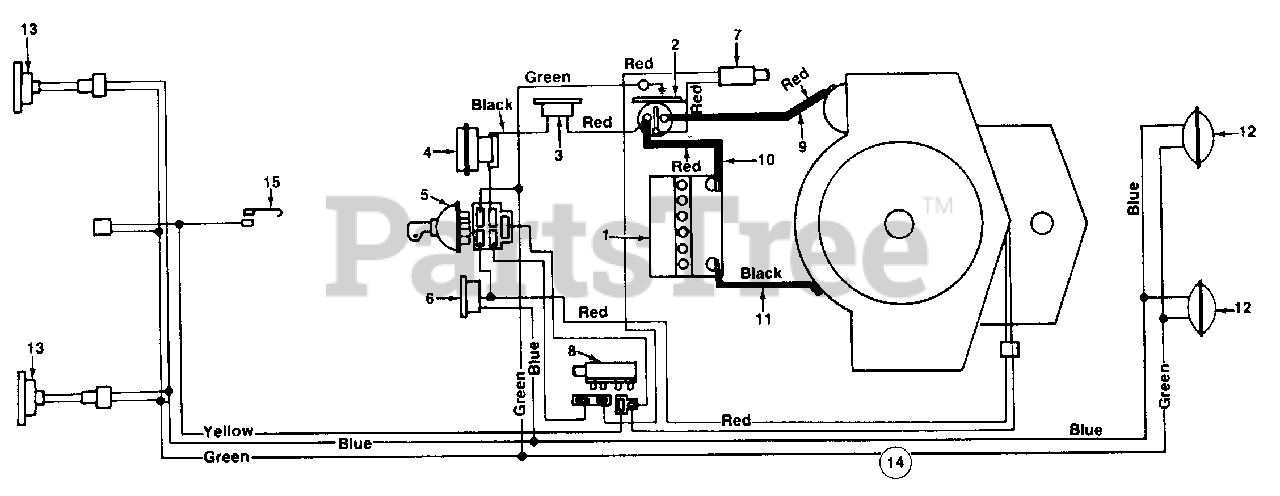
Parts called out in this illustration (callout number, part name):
1	Battery
2	Solenoid
3	Circuit Breaker
4	Ammeter
5	Ignition Switch
6	Light Switch
7	Safety Switch
8	Safety Switch
9	Electric Wire 14" Lg.
10	Electric Wire 7.5" Lg.
11	Ground Wire 7.5" Lg.
12	Headlight
13	Taillight
14	Wire Harness
15	Spring Switch
